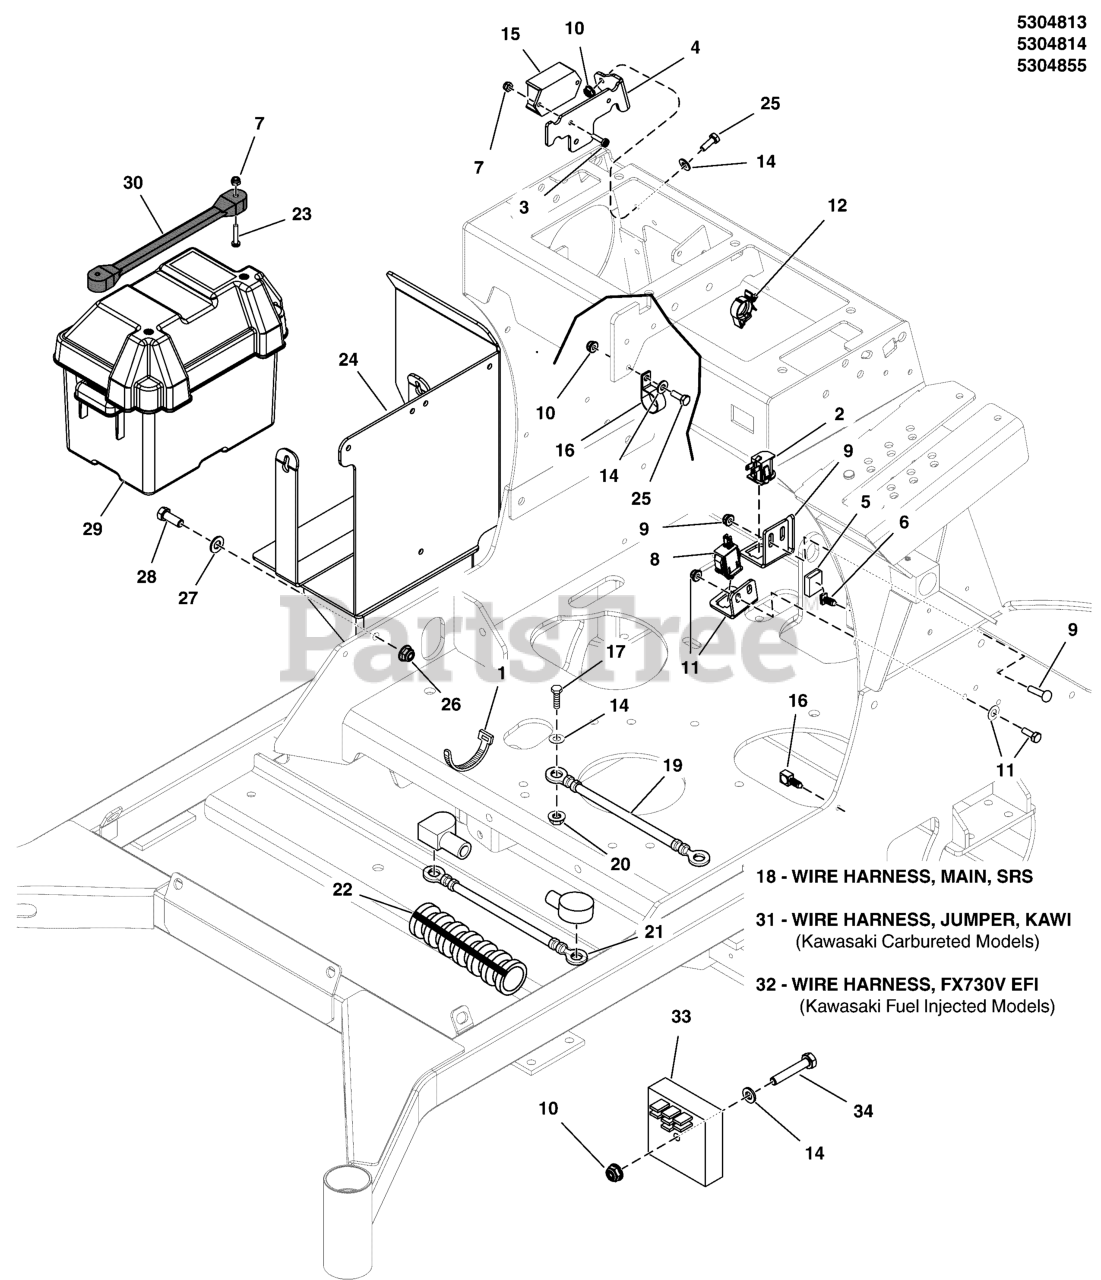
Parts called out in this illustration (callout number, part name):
1	TIE, SELF-LOCKING, 12"
2	SWITCH, SEAT
2	SWITCH, Push Button, NO, Black
3	SCREW, #10-24 X 3/4" ROUND PHILLIPS
4	PLATE, WIRE GUIDE / TDM MOUNT - BLK
5	PART OF WIRE HARNESS
6	FIR TREE MOUNT, PACKARD
7	NUT, Hex, Nylon Lock, #10-24
8	SWITCH, PLUNGER, NO, SINGLE POLE, SNAP-IN
9	Refer to: Operator Compartment Group
10	NUT, 1/4-20 Hex Nylock Flange
11	Refer to: Parking Brake Group
12	ROSEBUD LOOM CLIP
13	BATTERY, 11U1L, 350 CCA
14	WASHER, 1/4 SAE
15	MODULE, TIME DELAY, NO DIODE
16	CLAMP, VINYL INSULATED, 1.00
17	HHCS, 1/4-20 X 0.625, GR5, ZINC/CLEAR
18	WIRE HARNESS, MAIN, SRS
18	HARNESS, Wiring, Stand-On ZTR
19	BATTERY CABLE, NEG, 22, 1/4-5/16
20	NUT, 1/4-20 HEX SERR. FLANGE
21	BATTERY CABLE, POS, 22, 1/4-5/16
22	WIRE LOOM, 3/8 ID X 19 IN
23	SCREW, #10-24 X 1 RS, CZ
24	WELD, BATTERY BOX, STAND ON - RED
25	BOLT, 1/4"-20 X 3/4" GD5 YZ
26	NUT, 3/8 - 16 HEX NYLOCK FLANGE
27	WASHER, 3/8 SAE
28	BOLT, 3/8-16 X 1" GD5 CZ
29	BATTERY BOX, W/ DRAIN HOLE
30	STRAP, RUBBER
31	WIRE HARNESS, JUMPER, KAWI
32	WIRE HARNESS, JUMPER FX730V, EFI
32	HARNESS, JUMPER, KAWASKI EFI
33	MODULE, THROTTLE CONTROL, KAV DFI
34	BOLT, 1/4-20 X 1-1/2 GD5 CZ
